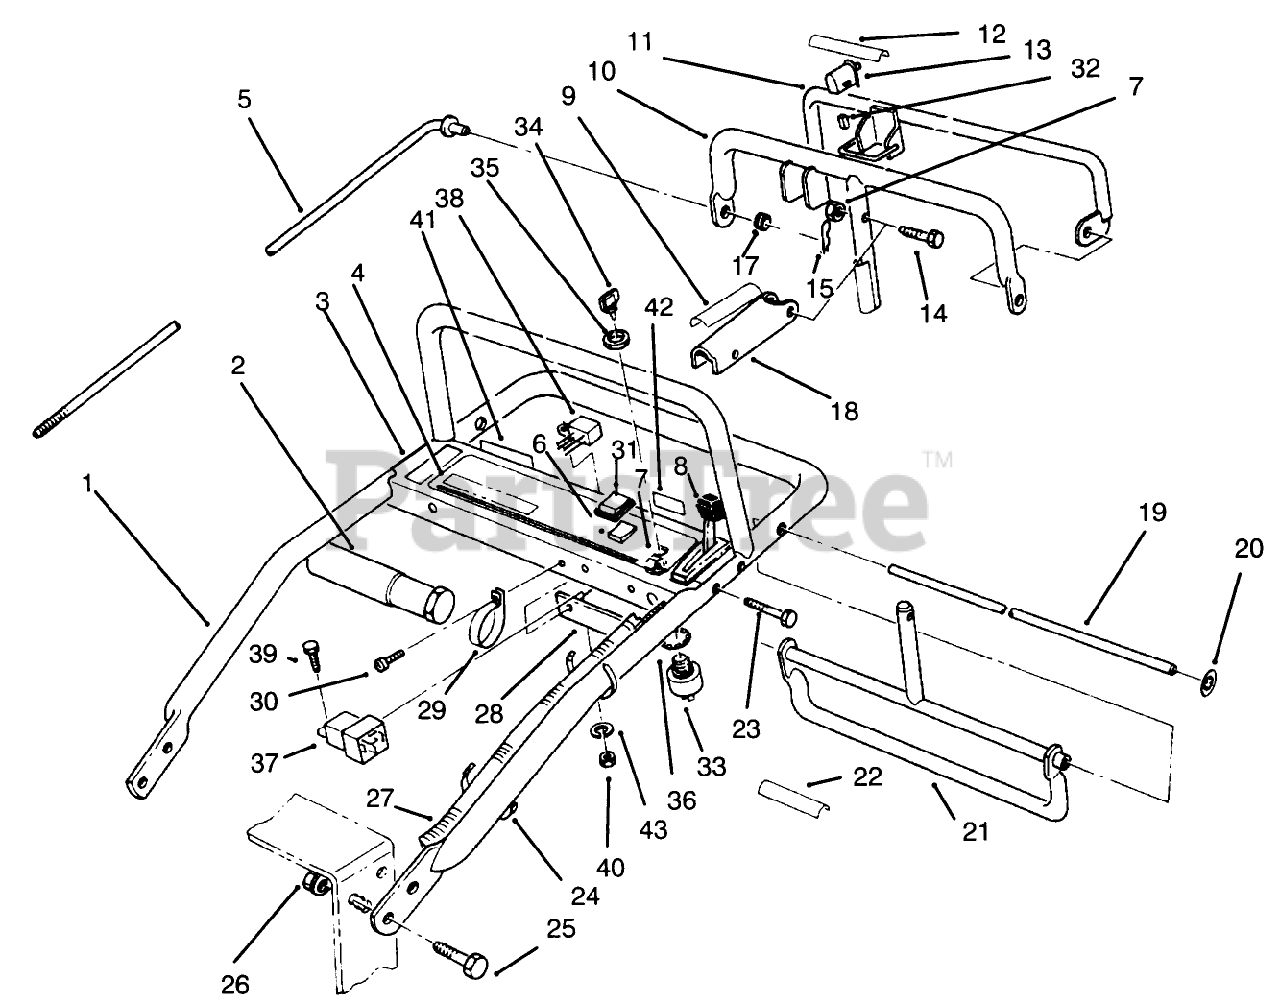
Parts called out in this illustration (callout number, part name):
1	Handle-Upper
2	TUBE-MANUAL
3	Panel-Control
4	DECAL-CONTROL PANEL
5	ROD-CONTROL
6	SWITCH
7	NUT-LOCK, NI
8	CONTROL-THROTTLE
9	DECAL-LEVER, PARKING
10	Bar
11	Bail
12	DECAL
13	SWITCH-BAIL
14	SCREW-SHH
15	PIN-COTTER
17	GROMMET-RUBBER
18	Lever-Parking Brake
19	PIVOT ROD
20	NUT-PUSH-ON, CIRCULAR
21	Control Pivot
22	DECAL
23	SCREW-SHH
24	TIE-CABLE
25	SCREW-HHF
26	NUT-HF
27	WIRE HARNESS
28	Panel-Bottom
29	CLAMP-R
30	SCREW-SHWH
31	BOOT-SWITCH
32	CONNECTOR-BODY
33	Switch-On/Off (Incl. Ref. #34-36)
34	KEY-IGNITION
35	NUT-HH
36	WASHER-TOOTH, INTERNAL
37	RELAY
38	Module
39	SCREW-HH
40	NUT-LOCK, NI
41	DECAL-INSTRUCTION, SAFETY
42	DECAL-INSTRUCTION
43	WASHER-LOCK/EXT
